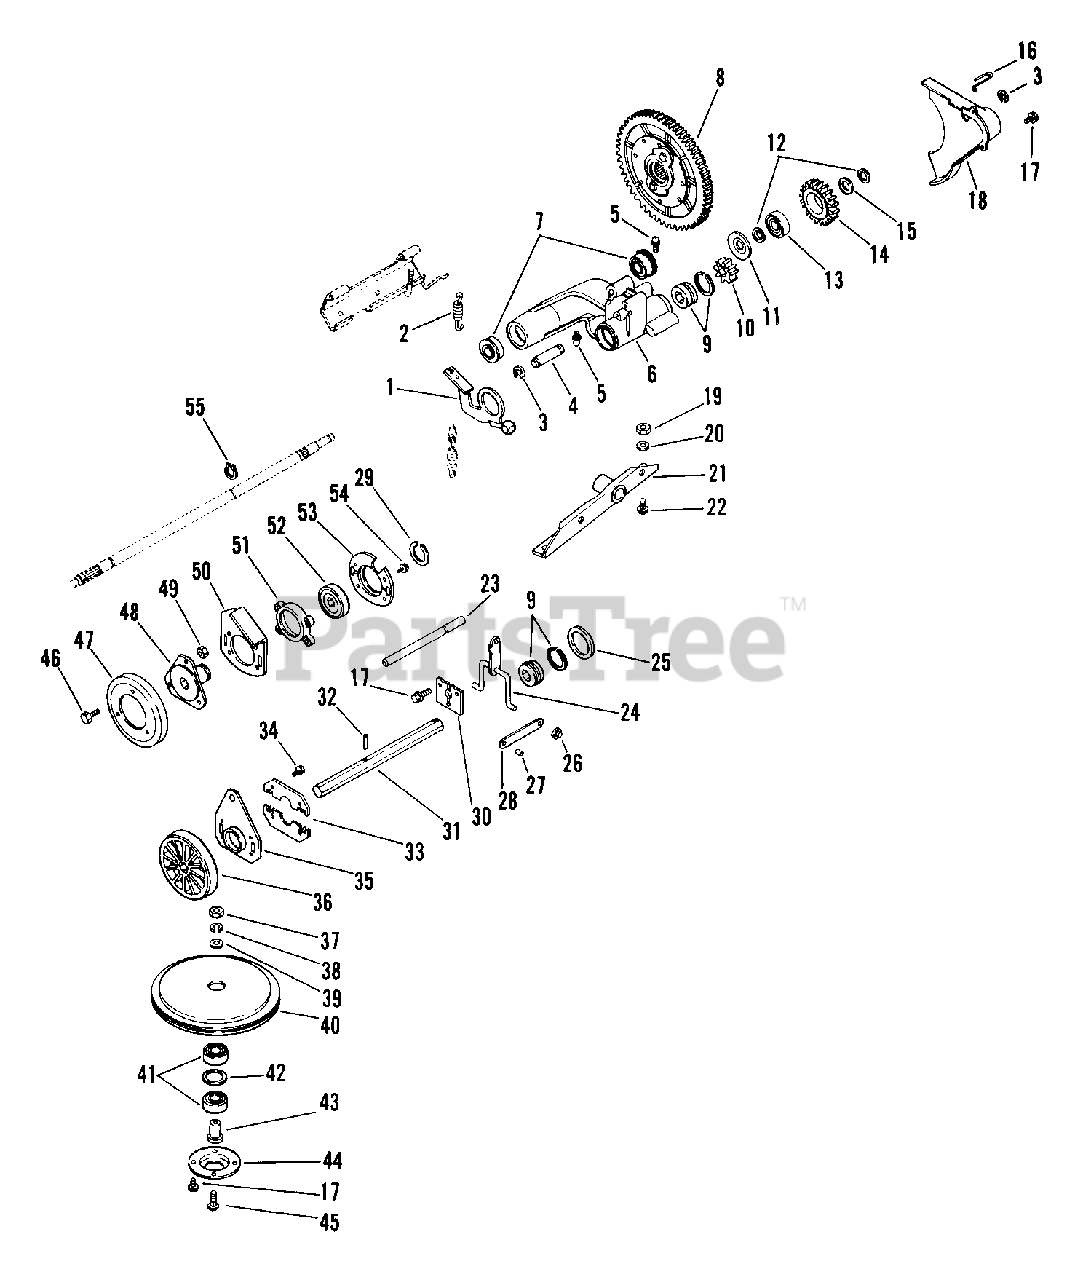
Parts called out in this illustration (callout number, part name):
1	DRIVE ACTUATOR WELDMENT
2	SG-TENS .051X.60X2.25 WLD 7.0
3	RG-RTNG-EXT .438X.035
4	IDLER SHAFT
5	SPIN DRIVE ZERK FITTING
6	DRIVE MOUNT
6	DRIVE CARRIER
7	BRG-BALL .625X1.383X.50
8	DIFFERENTIAL ASSEMBLY
9	BRG-BALL .562X1.375X.437
11	RETAINER
12	WSHR-FL-STL .520X.827X.062 YZ
13	BRG-BALL .500X1.38X.437
14	IDLER GEAR
15	WSHR-FL-STL .505X.880X.072 PL
16	CABLE RETAINER
17	SCR-TAP 12-24X.50 HWH PL TR
18	GEAR COVER
19	NUT-LK .312-18 GR A PL
20	WSHR-FL-STL.344X.688X.065PL
21	PIVOT CHANNEL WELDMENT
22	BLT-RDHDSQNK .312-18X.62SHTPL
23	ROD - GUIDE
24	SHIFT ARM WELDMENT
25	WSHR-FL-STL 1.390X2.00X.020 PL
26	PUSH NUT, .25
27	PIN-ROLL .125X.63
27	PIN-ROLL .125X.50
28	SHIFT LINK
29	RG-RTNG-EXT 1.00X.042
30	RETAINER PLATE
31	HEX SHAFT
32	PIN-ROLL .188X.88
33	THRUST PLATE
34	SCR-TAP 10-24X.375 HWH PL TR
35	GUIDE PLATE
36	FRICTION WHEEL ASSEMBLY
37	NUT-HEX .312-18
38	WSHR-LK .312X.097 PL HVY
39	WSHR-FL-STL .328X.875X.062 PL
40	FRICTION SHEAVE
41	BRG-BALL .625X1.375X.44
42	WSHR-FL-STL 1.062X1.344X.032PL
43	SPINDLE - BEARING
44	RETAINER - BEARING
45	BLT-RDHDSQNK .31-18X1.75 PL
46	BLT-HEX .25-20X.50 PL GR2
47	FRICTION DISC
48	FRICTION WHEEL HUB
49	NUT-LK-CTR .250-20 PL
50	BEARING PLATE
51	BEARING RETAINER
52	BRG-BALL 1.0X2.0X.56
53	BEARING RETAINER
54	TAPTITE M5-0.8X16MM H-FL-PL
55	RG-RTNG-EXT .625X.035
